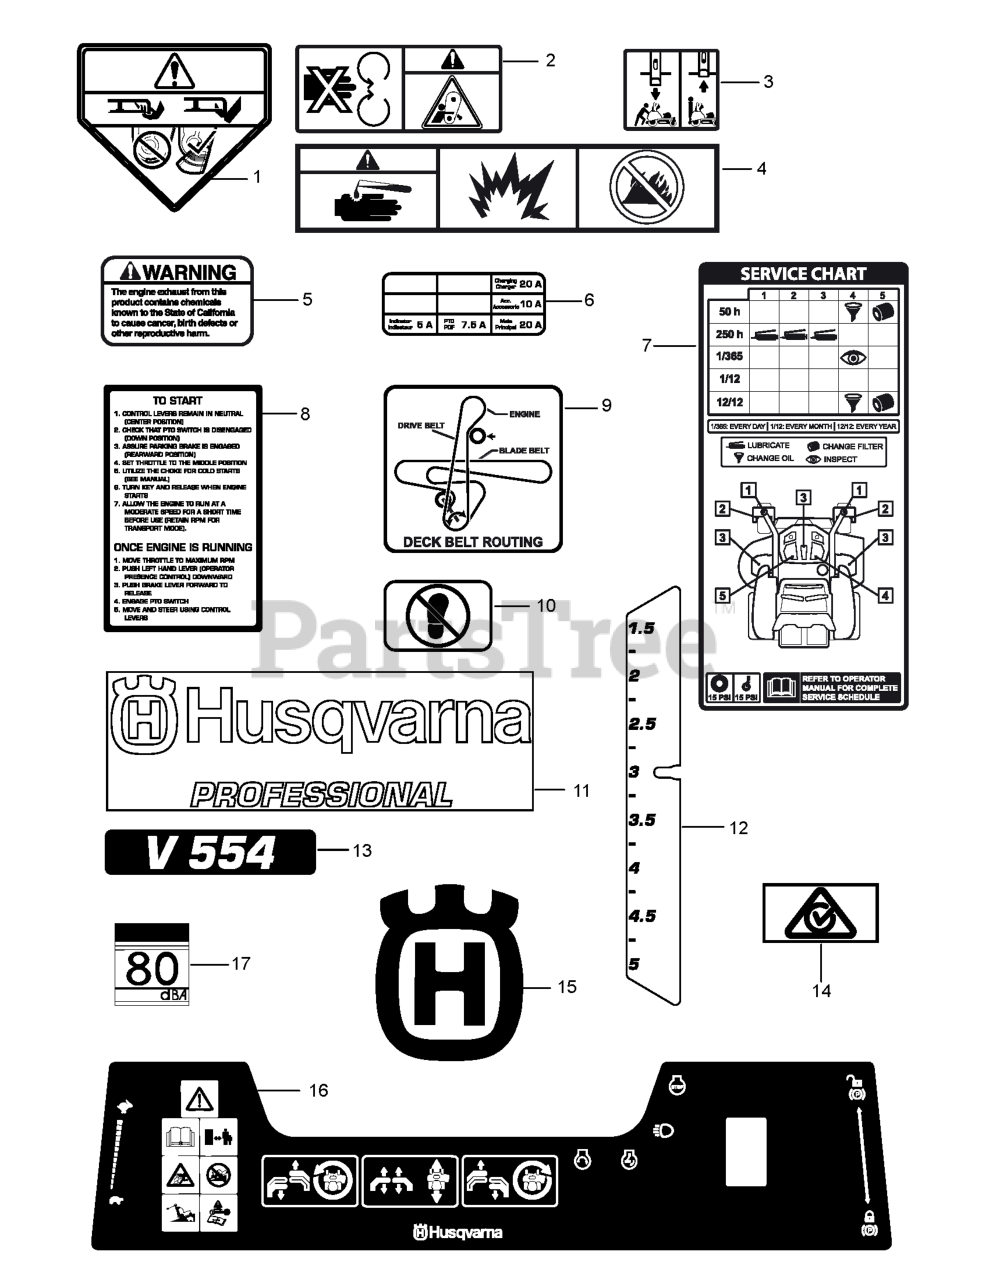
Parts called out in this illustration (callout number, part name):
1	DECAL, DECK DEFLECTOR, WARNING
2	DECAL, BELT DRIVE
3	DECAL ZTR INSTRUCTION GRAPHIC
4	EURO DECAL-BATTERY WARNIN6
5	DECAL.DECK.6MIL./DEF.SHLD.WARN
6	DECAL ZTR INSTRUCTION GRAPHIC
7	DECAL ZTR INSTRUCTION GRAPHIC
8	DECAL.STRAT.INSTRUCT.ENG.ONLY
9	DECAL BELT ROUTING DECAL DECAL
10	DECAL.DECK.6MIL.EURO.NOSTEP
11	DECAL ZTR INSTRUCTION GRAPHIC
12	DECAL ZTR INSTRUCTION GRAPHIC
13	DECAL ZTR INSTRUCTION GRAPHIC
14	DECAL CERTIFICATION DECAL EMCC
15	DECAL.BADGE.55MM.CROWNH.HUSQ
16	DECAL ZTR INSTRUCTION GRAPHIC
17	DECAL.80.DBA.AUSTRALIA
